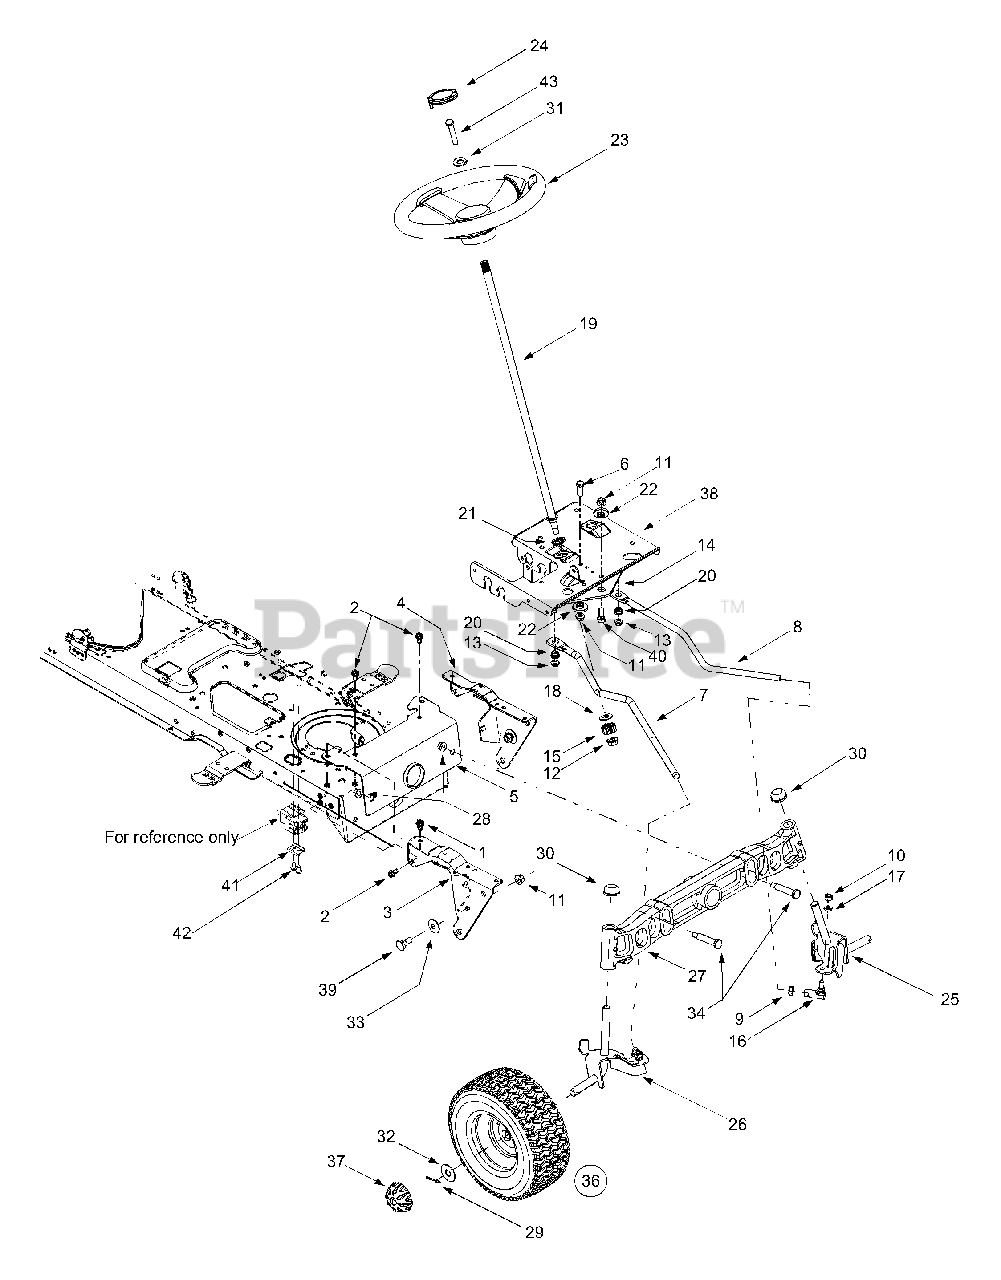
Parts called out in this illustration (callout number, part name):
1	Self-tapping Screw, 5/16-18 x .75
2	Self-tapping Screw, 16-18 x .625
6	Hex Cap Screw, 3/8-16 x 1 (Grade 5)
7	RH Drag Link
8	LH Drag Link
9	Jam Nut, 7/16-20 (Grade 2)
10	Hex Nut, 3/8-24 (Grade 2)
11	Flange Lock Nut, 3/8-16
12	Flange Lock Nut, 7/16-20
13	Flange Lock Nut, 5/16-18
14	Steering Gear, 11/90 Ratio
15	Steering Pinion Gear
16	Ball Joint, 7/16-20
17	Lock Washer, 3/8
18	Flat Washer, .51 x 1.12 x .06
19	Steering Shaft, .625 OD x 24.4
20	Plastic Bushing, .38 ID
21	Hex Flange Bearing, 5/8
22	Shoulder Spacer, .38 ID
23	Steering Wheel: 3 Spoke
24	Steering Wheel Cap
25	LH Axle Assembly, .75 Diameter
26	RH Axle Assembly, .75 Diameter
27	Cast Iron Pivot Bar w/ Fittings, .75
28	Flange Lock Nut, 3/8-16
29	Cotter Pin
30	Push Cap, .750
31	Bell Washer, .34 x .872
32	Flat Washer, .635 x 1.589 x .06
33	Bell Washer, .39 x 1.13 x .062
34	Shoulder Screw, .5 x 2.2, 3/8-16
37	Hub Cap
39	Shoulder Screw, 3/8-16
40	Hex Screw 3/8-16 x 1.0
41	Switch Plate
42	AB Screw #10-16 x 0.5
43	Hex Bolt, 5/16-18 X 1
